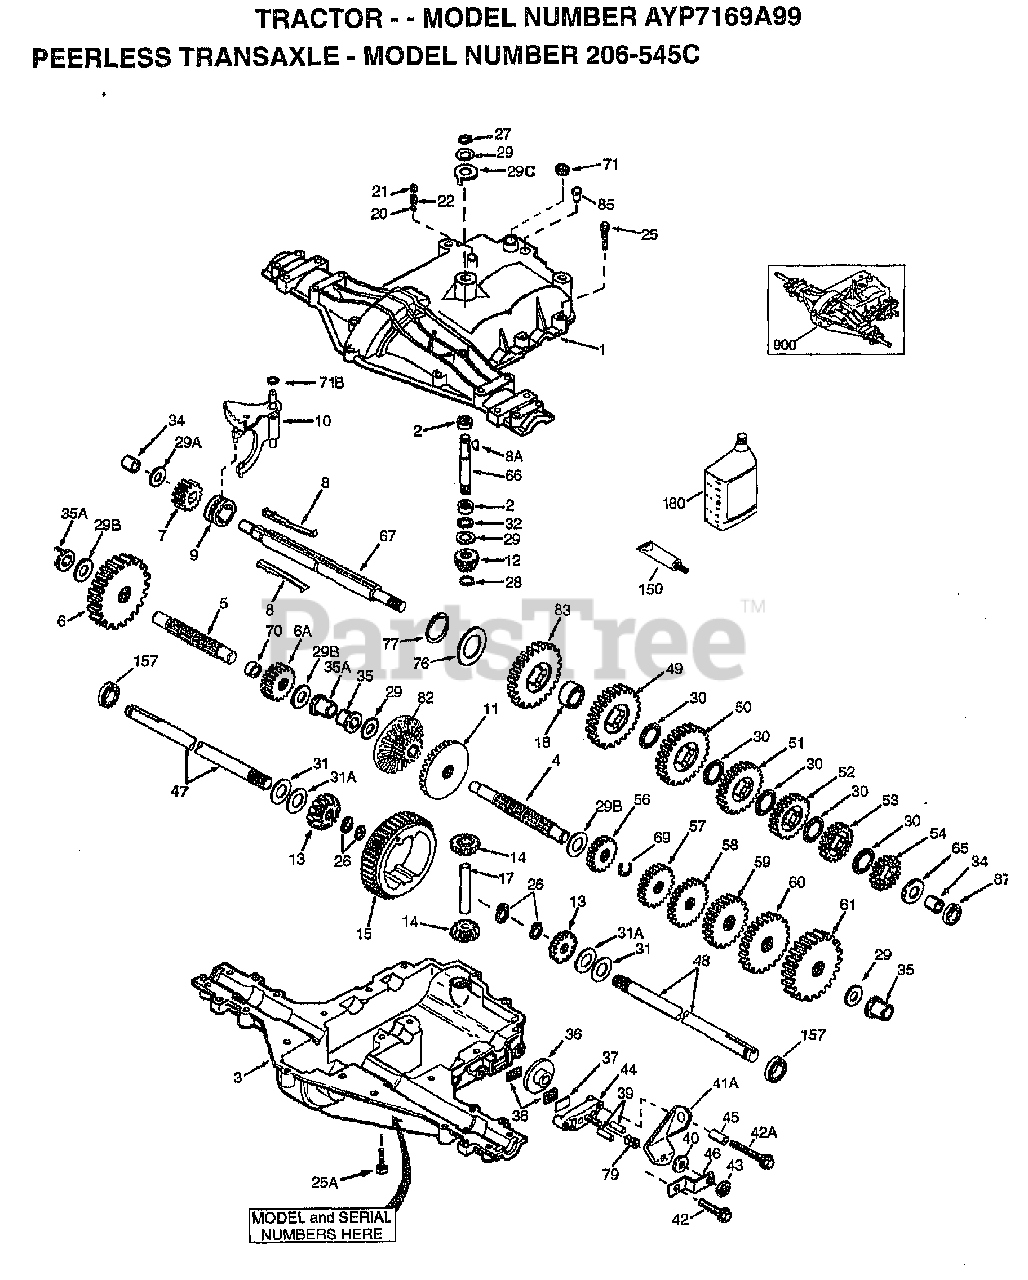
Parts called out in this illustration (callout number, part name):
1	TRANSAXLE COVER
2	NEEDLE BEARING 5/8" ID
3	TRANSAXLE CASE
4	COUNTERSHAFT
5	OUTPUT SHAFT
6	SPUR GEAR (38 TEETH)
6A	SPUR GEAR (15 TEETH)
7	SPUR GEAR (11 TEETH)
8A	KEY, WOODRUFF
9	COLLAR, SHIFTER
10	SHIFT ROD & FORK
11	BEVEL GEAR (30 TEETH)
12	INPUT BEVEL PINION (13TEETH)
13	BEVEL GEAR (13 TEETH)
14	BEVEL GEAR (13 TEETH)
15	RING GEAR (43 TEETH)
18	SPACER, NEUTRAL
21	SCREW, 3/8-16 X 3/8"
25A	SCREW 1/4-20 X 1-3/8"
26	RING RETAINER
27	RING, RETAINER
28	RETAINING RING
29	WASHER THRUST
29B	WASHER THRUST
29C	P/N CONFLICT - CHECK WITH SUPPLIER
30	WASHER THRUST
31A	FLAT WASHER
32	OIL SEAL 5/8"
34	BUSHING 9/16"
35	FLANGED BUSHING 5/8" ID
35A	FLANGED BUSHING 3/4"
37	PLATE BRAKE PAD
41A	BRAKE LEVER
42A	SCREW, 1/4-20 X 2-1/4
43	LOCKNUT 5/16-24
44	HOLDER BRAKE PAD
46	BRKT BRAKE LEVER
49	SPUR GEAR (29 TEETH)
50	SPUR GEAR (27 TEETH)
51	SPUR GEAR (23 TEETH)
52	SPUR GEAR (19 TEETH)
53	SPUR GEAR (16 TEETH)
54	SPUR GEAR (15 TEETH)
56	SPUR GEAR (11 TEETH)
57	SPUR GEAR (13 TEETH)
58	SPUR GEAR (17 TEETH)
59	SPUR GEAR (21 TEETH)
60	SPUR GEAR (24 TEETH)
61	SPUR GEAR (25 TEETH)
66	INPUT SHAFT
67	SHIFTER & BRAKE SHAFT
69	RETAINING RING
70	SPACER .890
71	SEAL SQUARE CUT
76	WASHER, THRUST
77	INVERTED RETAINING RING
82	BEVEL & SPUR GEAR (30 & 13 TEETH)
83	SPUR GEAR (27 TEETH)
85	OIL FILL PLUG
150	LIQUID GASKET RTV SILICONE
180	GEAR OIL 80W90
900	REPLACEMENT TRANSAXLE
